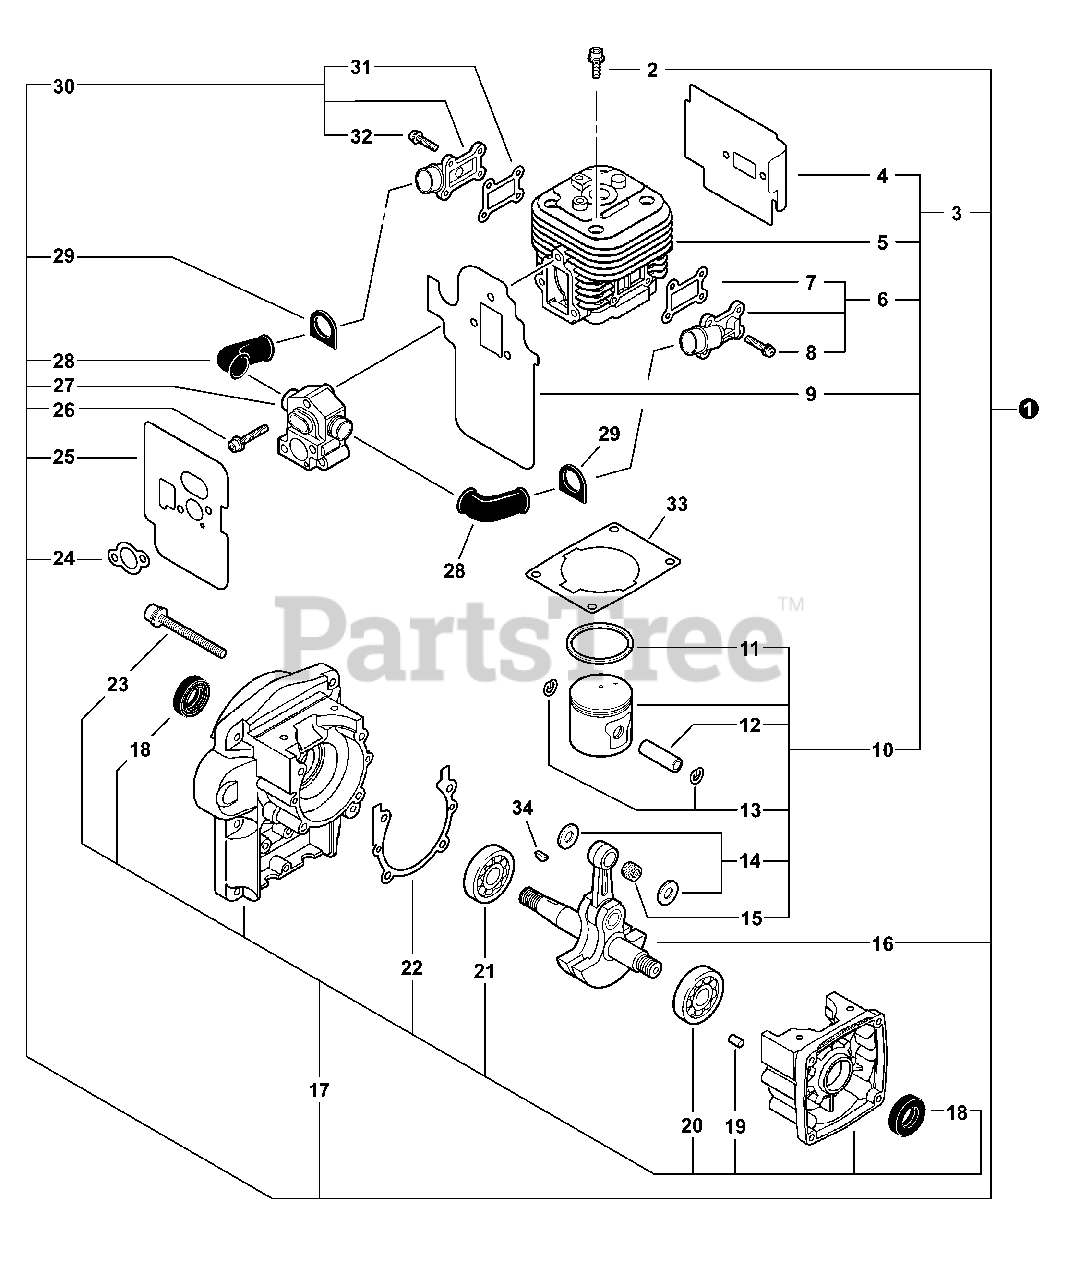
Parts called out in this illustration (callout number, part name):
1	SHORT BLOCK -- SB1105
2	SCREW - 5×22
3	CYLINDER/PISTON KIT
4	SHIELD, EXHAUST
5	CYLINDER
6	REED VALVE KIT - OUTER
7	GASKET, INTAKE
8	SCREW - 4
9	GASKET, INTAKE
10	PISTON KIT
11	RING, PISTON
12	PIN, PISTON
13	RING, RETAINING - 8
14	WASHER - 10
15	BEARING, NEEDLE - 10
16	CRANKSHAFT ASSY
17	CRANKCASE KIT
18	SEAL, OIL
19	PIN - LOCATING
20	BEARING, BALL - 6202
21	BEARING, BALL - 6302
22	GASKET, CRANKCASE
23	SCREW - 5×40
24	GASKET, INTAKE
25	SHIELD, INTAKE
26	SCREW - 5×35
27	VALVE ASSY
28	HOSE, AIR
29	GROMMET
30	REED VALVE KIT - INNER
31	GASKET, INTAKE
32	SCREW - 4
33	GASKET, CYLINDER
34	KEY - 3×14
